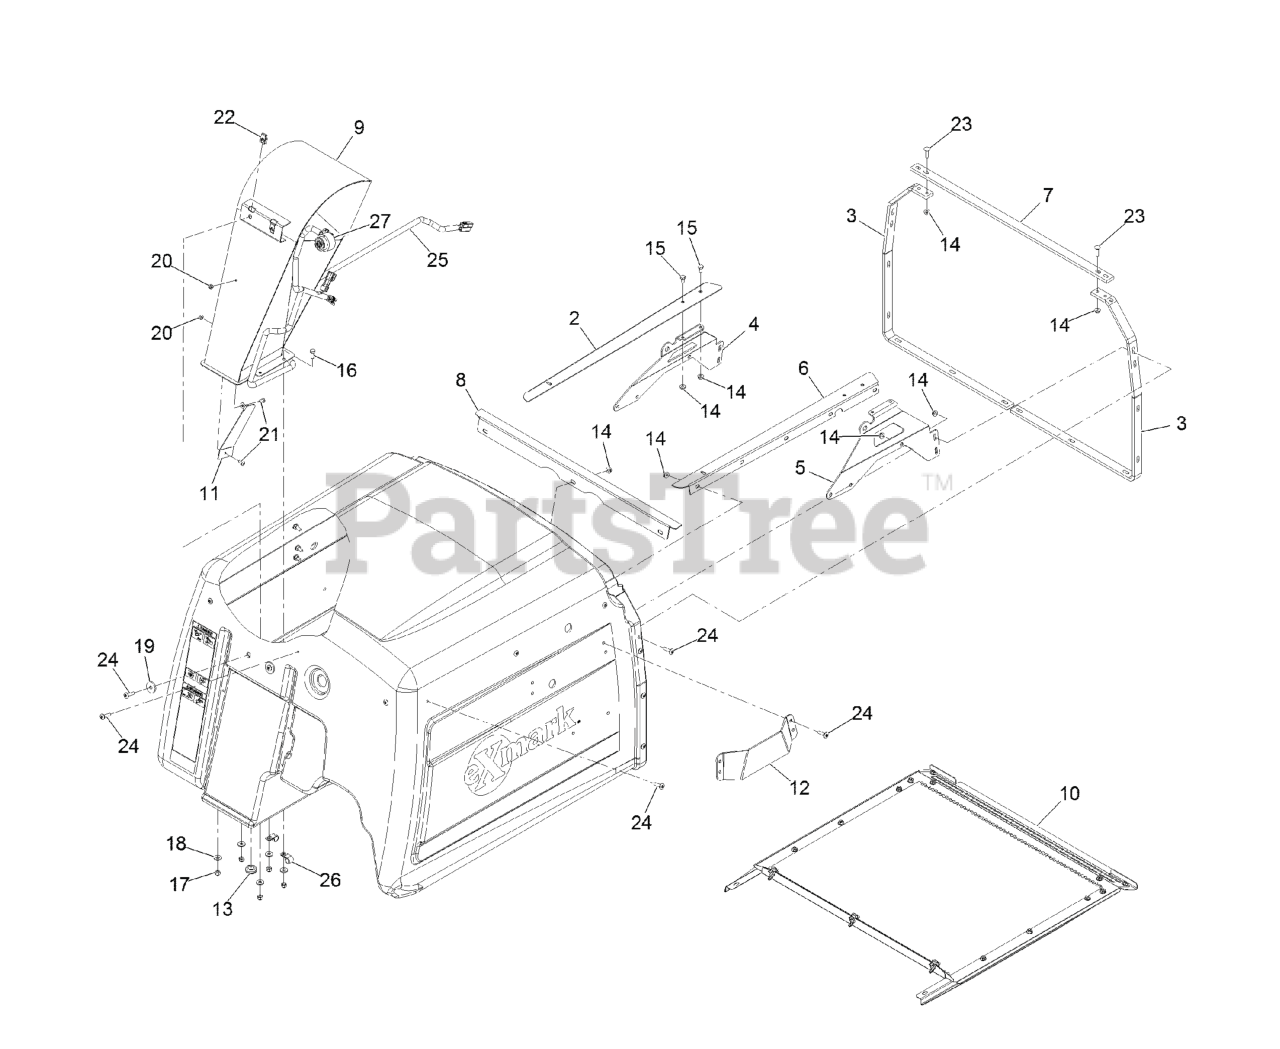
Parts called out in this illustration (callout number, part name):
2	ANGLE-SCREEN TRACK, RH
3	REINFORCEMENT-HOPPER
4	BRACE-DOOR PIVOT, RH
5	BRACE-DOOR PIVOT, LH
6	ANGLE-SCREEN TRACK, LH
7	BRACKET-FRAME CONNECT
8	CHANNEL-SCREEN, FRONT
10	HOPPER SCREEN ASM
11	DEFLECTOR-DISCHARGE CHUTE
12	PLATE-GUARD
13	GROMMET
15	SCREW-HH
16	SCREW-HH
17	NUT-LOCK, NI
18	WASHER-FLAT
20	NUT-LOCK, NI
21	SCREW-PTH
23	SCREW-CARR
24	SCREW-TTH
25	HARNESS-WIRE, HOPPER
26	CLIP-LOOM
27	ALARM-TONE, DUAL
